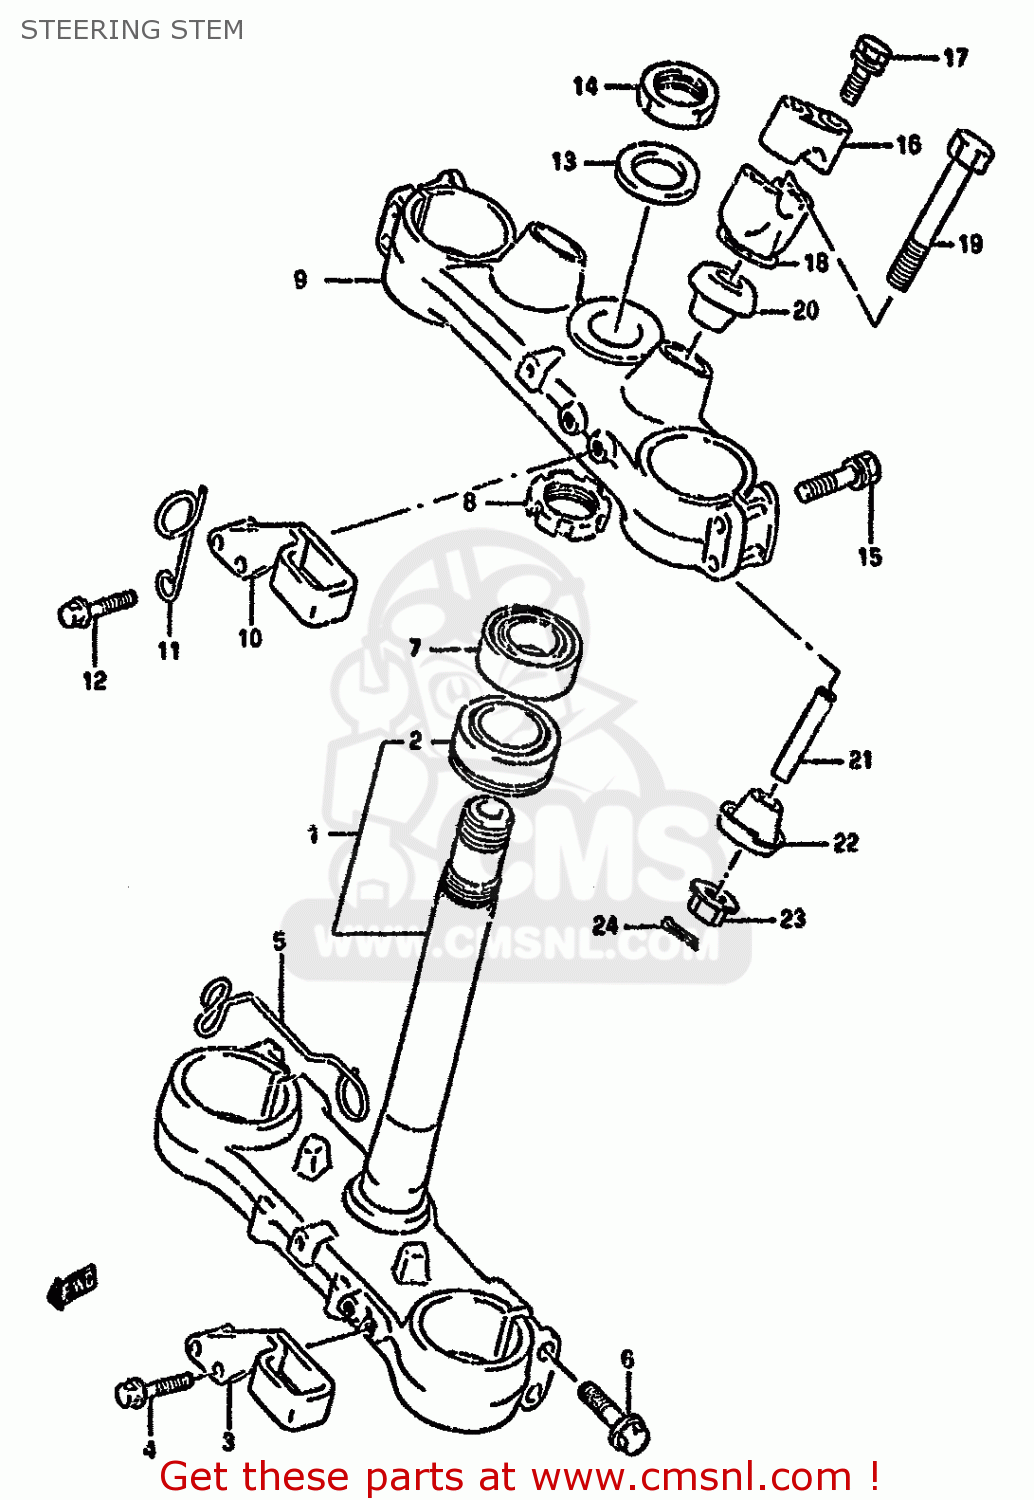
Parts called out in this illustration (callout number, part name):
1	STEM,STEERING
2	BEARING(30X52X16)
3	GUIDE,CLUTCH CABLE
4	BOLT,GUIDE
5	GUIDE,METER CABLE
6	BOLT,STEM 8X45
7	BEARING(30X52X16)
8	NUT,STEERING
9	HEAD,STEERING STEM
10	GUIDE,HOSE
11	GUIDE,CLUTCH CABLE
12	BOLT,GUIDE
13	WASHER,STEM HEAD
14	NUT,STEM HEAD
15	BOLT,STEM 8X45
16	HOLDER,HANDLEBAR
17	BOLT,HANDLE HOLDER(8X35)
18	HOLDER,HANDLE UNDER
19	BOLT,LWR HOLDER
20	CUSHION,RUBBER UPR
21	SPACER
22	CUSHION,RUBBER UNDER
23	NUT
24	COTTER PIN
